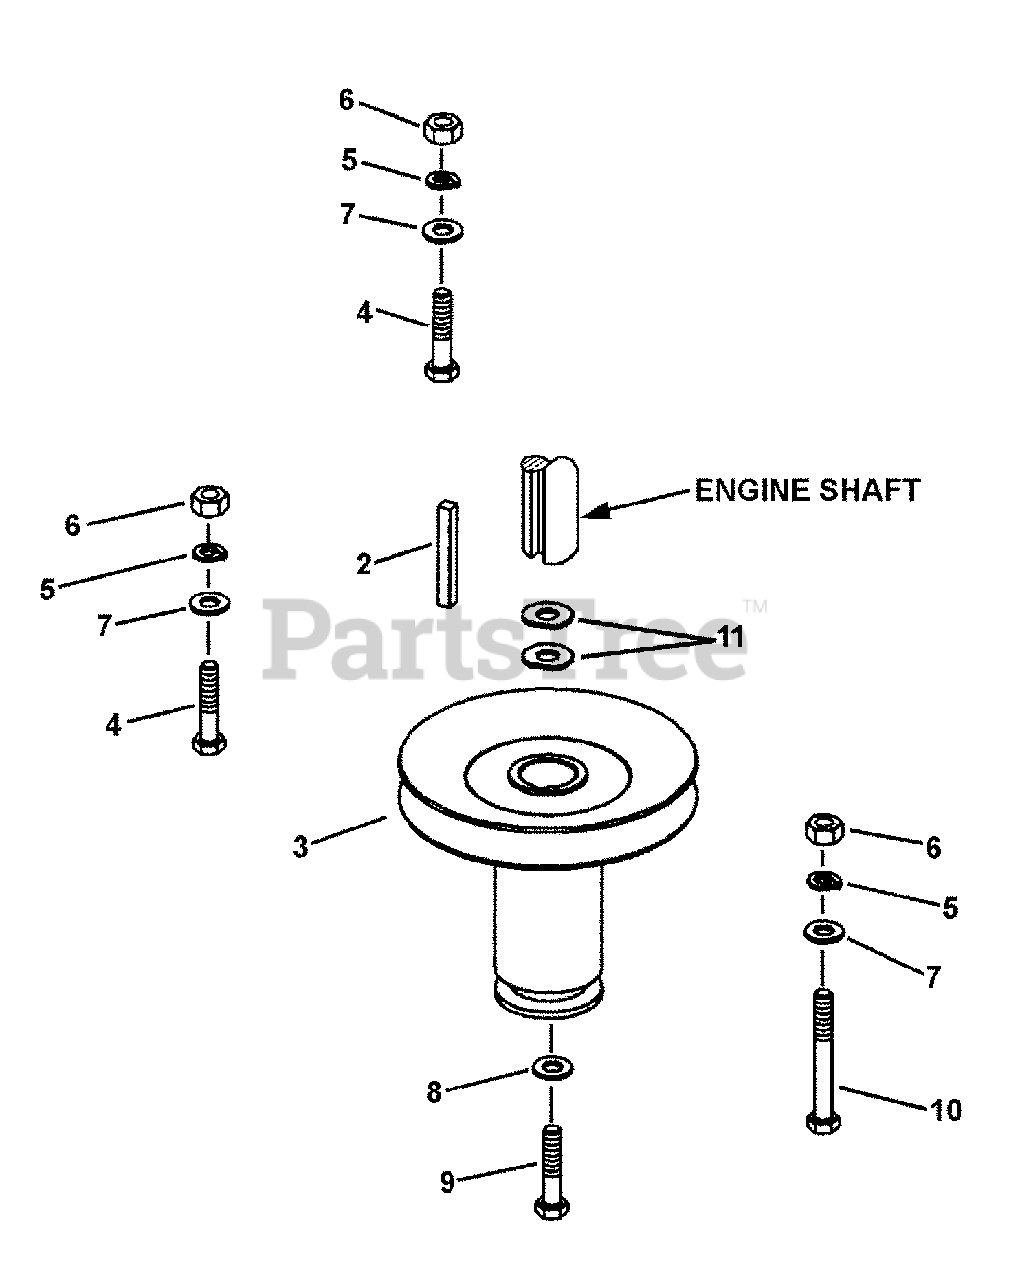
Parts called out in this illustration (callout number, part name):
1	*ENGINE, 7HP B&S Intek
2	KEY 1/4" Square x 2" long
2	KEY 1/4" Square x 1" long
3	PULLEY, Engine
4	SCREW, 5/16-24 x 1-1/2" Hex Head Cap, GR 2
5	WASHER, 5/16" Split Lock
6	NUT, 5/16-24 Hex
7	WASHER, 5/16" Flat
8	WASHER, 3/8" Split Lock
9	SCREW, 3/8-24 x 1" Hex Head Cap, GR 5
10	SCREW, 5/16-24 x 2-1/2" Hex Head Cap, GR 5
11	SPACER, .06 Blade Hub
